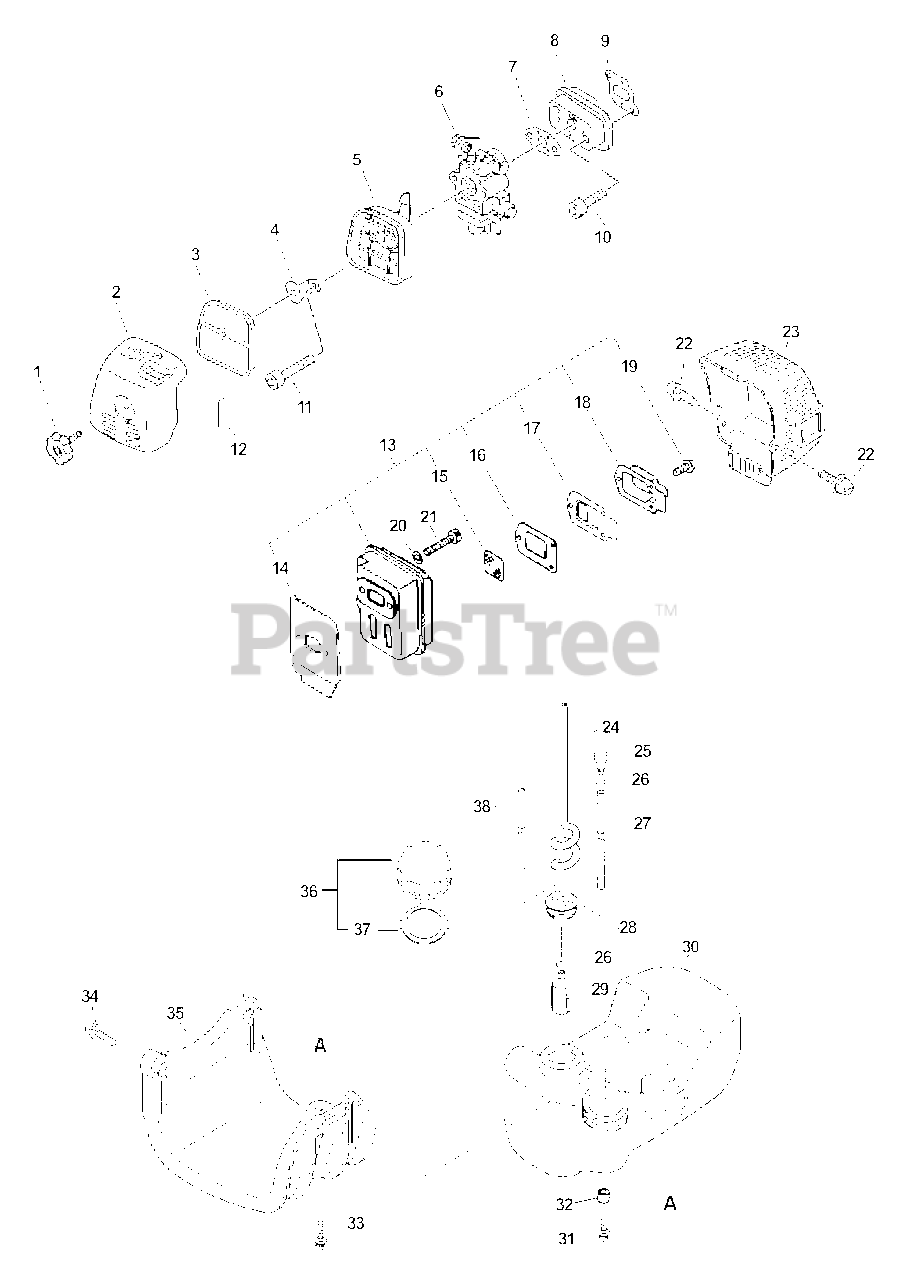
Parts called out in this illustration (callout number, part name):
1	THUMBSCREW
2	COVER, AIR FILTER
3	FILTER, HEAVY-DUTY AIR
4	PLATE, PREVENT
5	CASE, AIR FILTER
6	CARBURETOR - WYJ-192
7	GASKET, CARBURETOR
8	INSULATOR, INTAKE
9	GASKET, INTAKE
10	BOLT 5×25
11	SCREW 5×55
12	LABEL - CHOKE
13	MUFFLER ASSY
14	GASKET, EXHAUST
15	SCREEN, SPARK ARRESTER
16	GASKET, EXHAUST
17	GUIDE, EXHAUST
18	OUTLET, EXHAUST
19	SCREW 4×10
20	WASHER, FLAT 5.5×10×0.8
21	BOLT 5×55
22	BOLT 5×12
23	COVER, MUFFLER
24	PIPE, FUEL 3×6×165
25	VENT ASSY
26	CLIP Ø6.5 MM
27	PIPE, FUEL 3×6×100
28	GROMMET, FUEL
29	FILTER, FUEL
30	TANK, FUEL
31	SCREW 5×16
32	SPACER 6.2×7.8×6
33	SCREW 5×20
34	BOLT 5×22
35	GUARD, FUEL TANK
36	CAP ASSY, FUEL
37	GASKET, FUEL CAP
38	PIPE, FUEL 3×6×60 CLEAR
